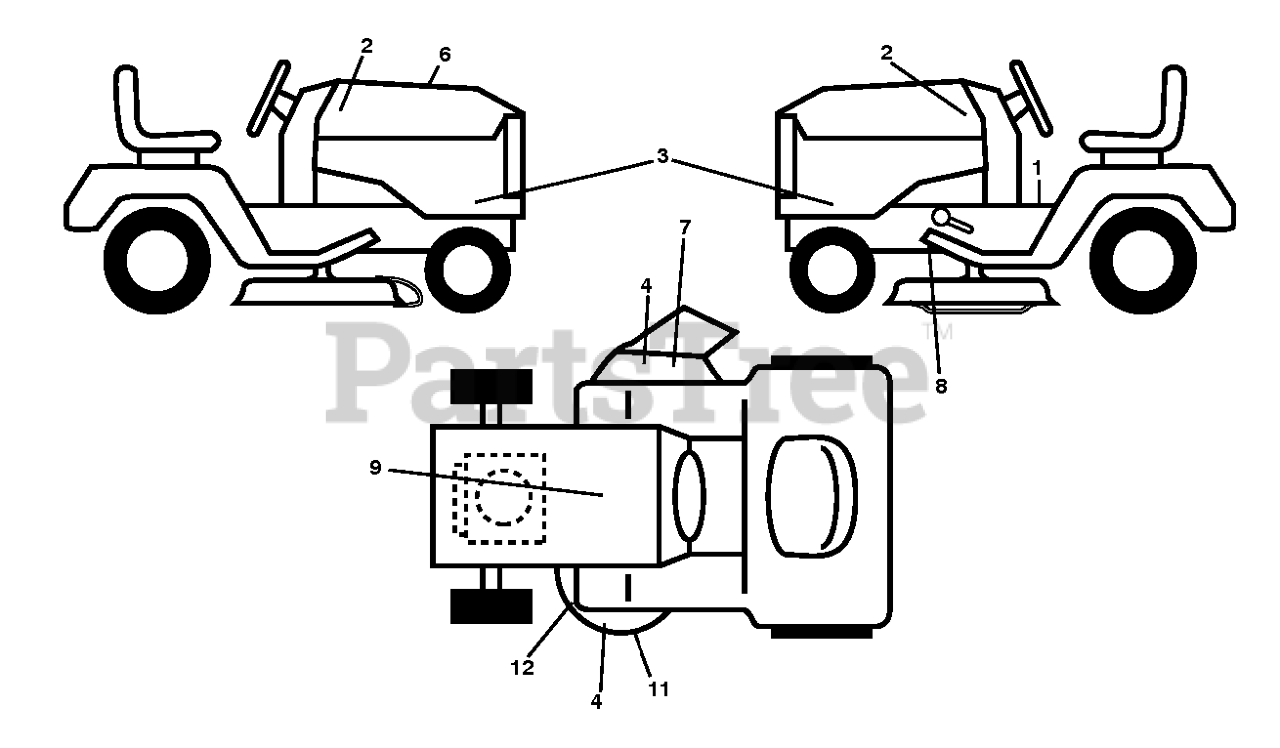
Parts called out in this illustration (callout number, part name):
1	DECAL.FENDER.WARNING.ENGLISH
2	DECAL.BADGE.170MM.TEXTLOGO.
3	DECAL.SDPNL.YT42DXLS.SET
4	DECAL.DECK.6MIL.EURO.NOSTEP
6	DECAL.RPL.KOH.KT7.TLB.42F.K46
7	DECAL.TRACT/ZTR.DECKWARN.HUSQ
8	DECAL.PEDAL.HUSQ.CROWN
9	DECAL BTRY SYMBOLS
11	DECAL.HV.REINFORCED.DECKS.2012
12	DECAL.V-BELT.SCH.42/46"MEC/ELE
